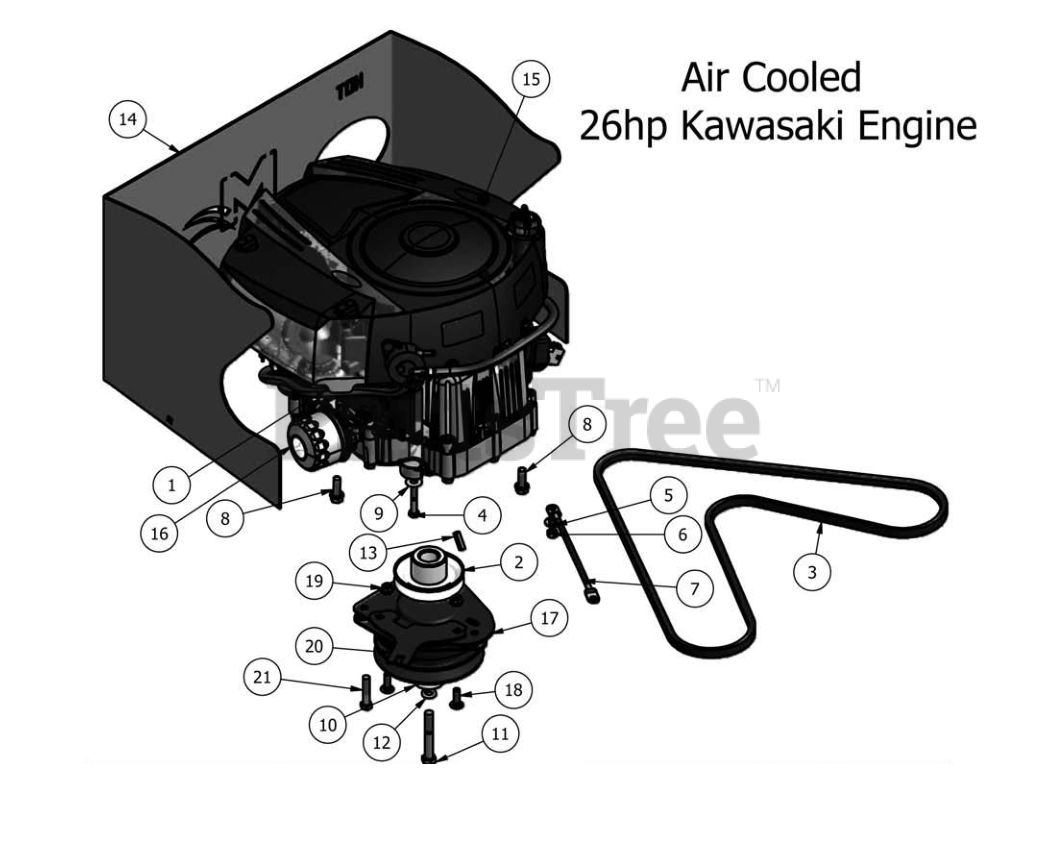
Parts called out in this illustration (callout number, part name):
1	26 hp Kawasaki
2	3-3/4" Motor Pulley
4	3/8 x 3 1/2 Grade 5 Hex Bolt
5	5/16 Lock Washer Zinc
6	5/16-18 Hex Nuts Zinc
7	Ground Cable
8	3/8 x 1-1/8 Hex Washer Head Engine Bolt
9	5/16 USS Flat Washer Zinc
10	Spring Blade Cupped Washer
11	MZ Crank Shaft Bolt
12	7/16 Lock Washer Zinc
13	1/4" x 1" Key
14	Engine Rear Plate
15	Air Filter 26Hp MZ
16	Oil Filter 26Hp MZ
18	5/16" x 1" Carriage Bolt
19	5/16" Flange Nut
20	clutch Holder
21	3/8-16 x 3 1/2 Hex Bolt (Clutch Stop)
